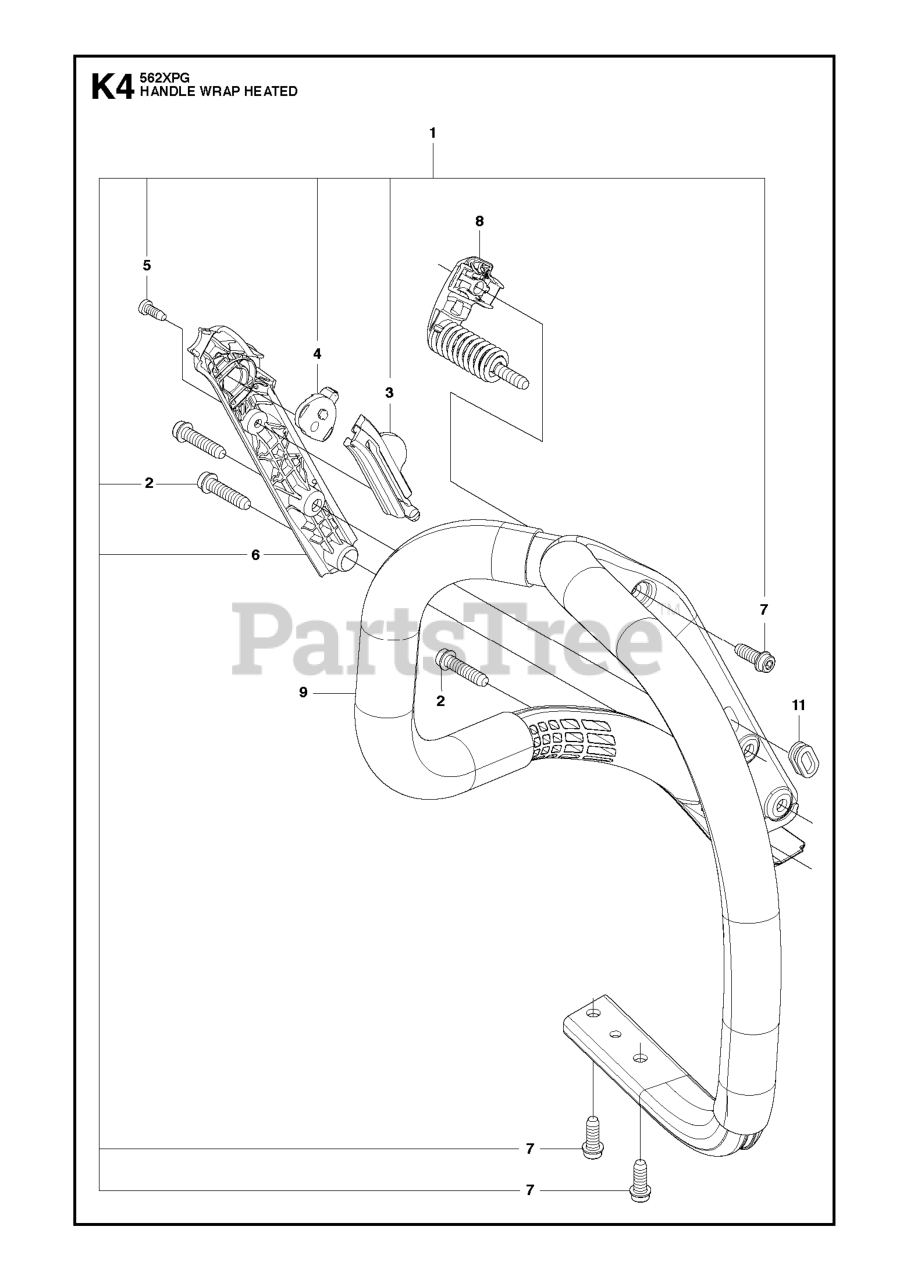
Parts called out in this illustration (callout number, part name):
2	SCREW
3	CONTACT PLATE
4	HANDLE
5	SCREW
6	COVER
7	SCREW IHSCFT
8	ANTIVIBRATION ELEMENT
9	HANDLE WRAP W
